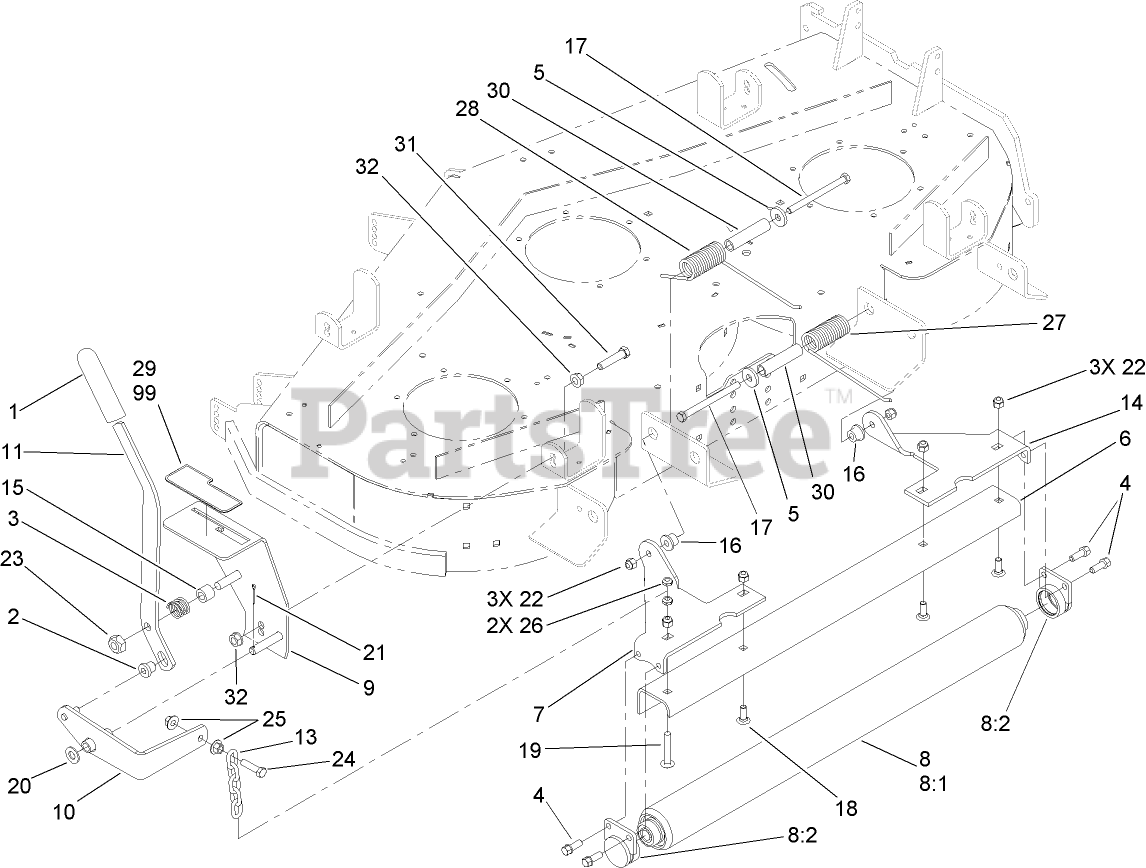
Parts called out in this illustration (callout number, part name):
1	GRIP-LEVER
2	BUSHING-PULLEY
3	SPRING-COMPRESSION
4	SCREW-HWH
5	WASHER
6	SCRAPER-ROLLER
7	MOUNT-ROLLER, LH
8	ROLLER ASM
8:1	ROLLER-STRIPER
8:2	HUB ASM
9	STRIPER PLATE ASM
10	CRANK ASM
13	CHAIN-STRAIGHT, 5 LINK
14	MOUNT-ROLLER, RH
15	SPACER
16	BUSHING-FLANGE
17	SCREW-HH
18	SCREW-CARR
19	SCREW-CARR
20	WASHER-FLAT
21	PIN-COTTER
22	NUT-LOCK, NI
23	NUT-HEX
24	SCREW-HH
25	NUT-FLANGE
26	NUT-LOCK, NI
27	SPRING-TORSION
28	SPRING-TORSION
30	SPACER-WHEEL, LONG
31	SCREW-HH
32	NUT-HF
99	DECAL-STRIPER ROLLER, CE
